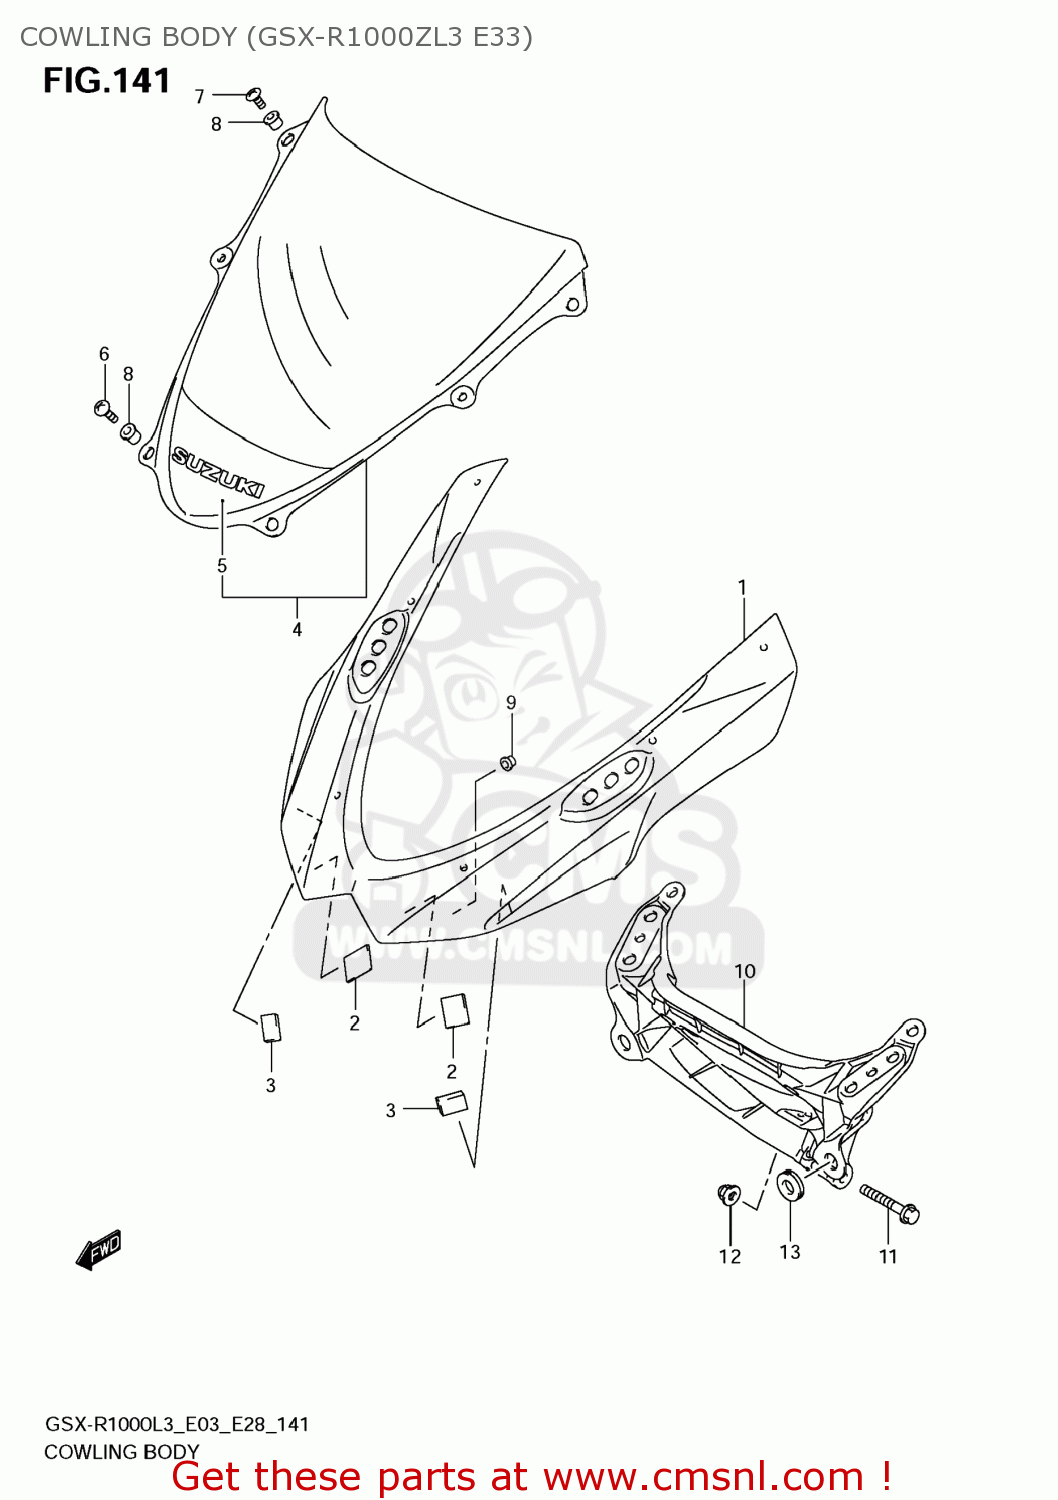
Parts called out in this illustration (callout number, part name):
1	BODY,COWLING
2	FASTENER
3	FASTENER,COWLING
4	WINDSCREEN
5	TAPE,WINDSCREEN
6	SCREW(5X18)
7	SCREW(5X15)
8	NUT
9	CUSHION
10	BRACE,COWLING
11	BOLT
12	NUT
13	CUSHION
